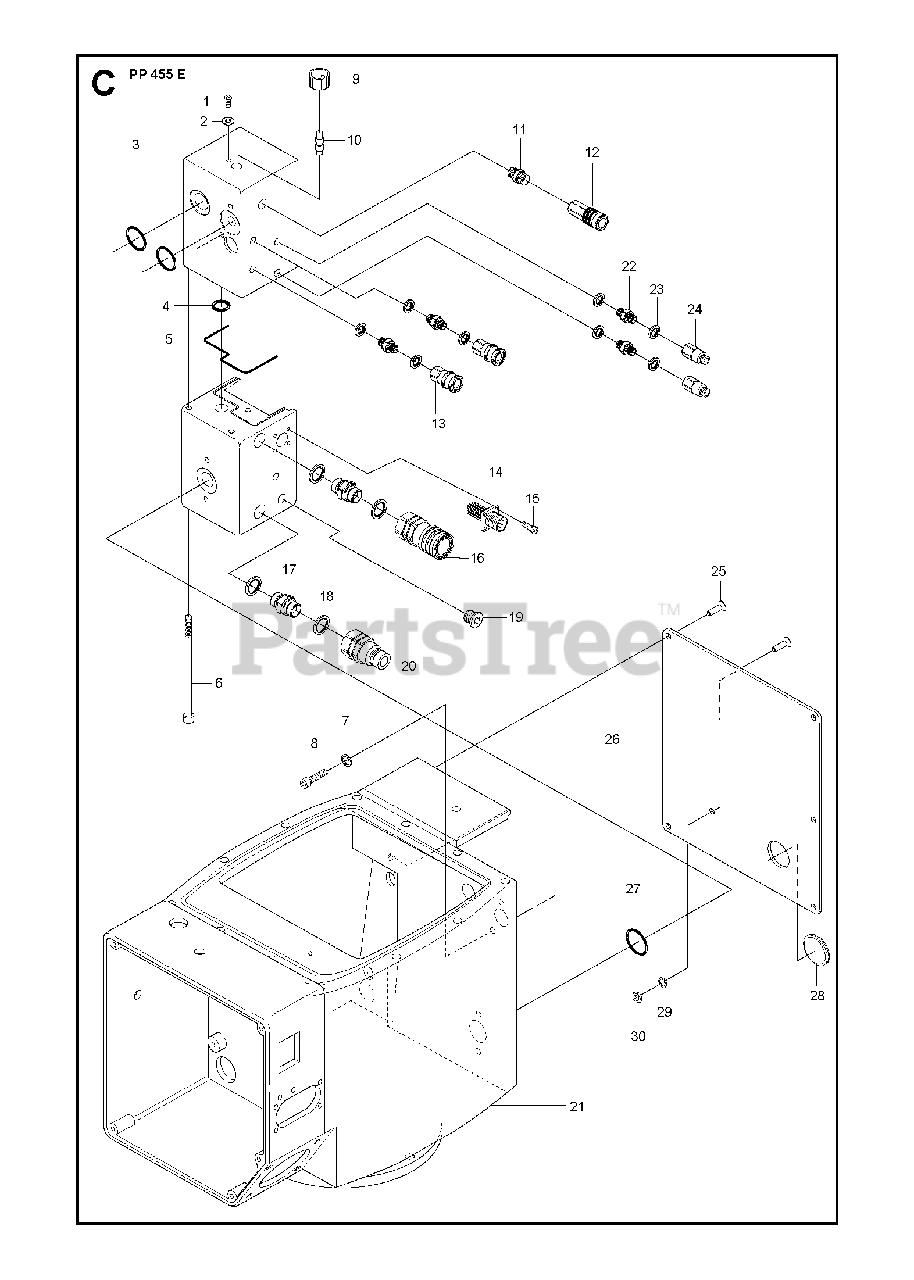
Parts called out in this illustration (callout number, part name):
2	WASHER
21	HYDRAULIC TANK
23	SEALING WASHER
